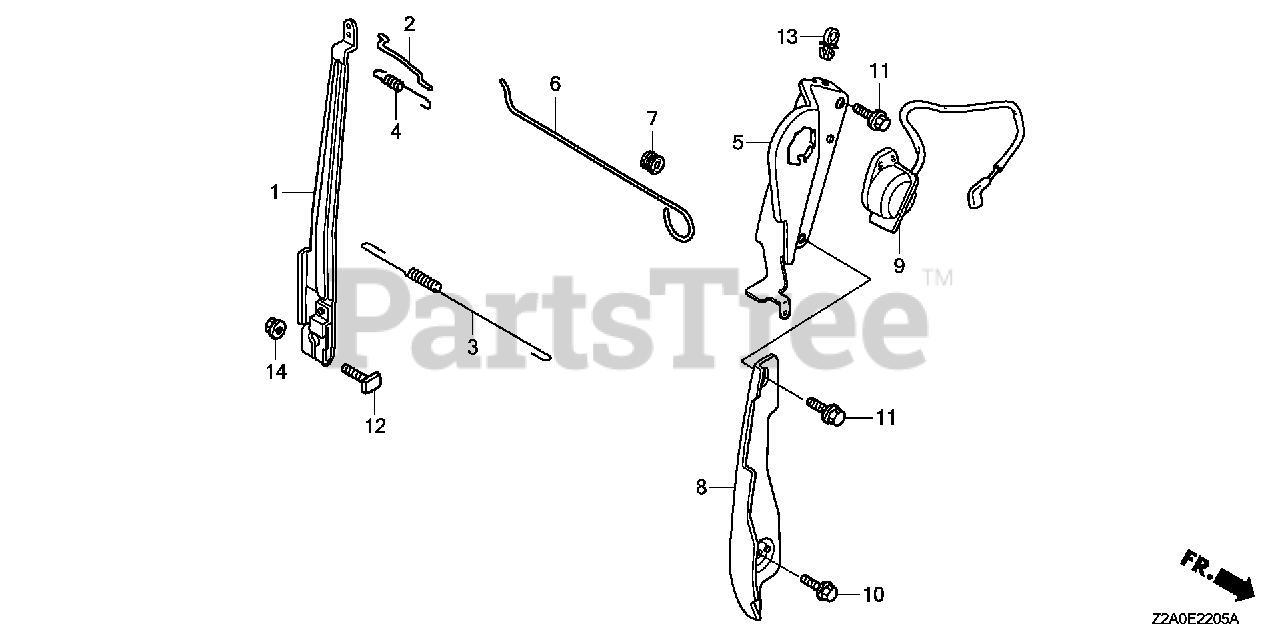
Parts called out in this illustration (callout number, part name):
1	ARM, GOVERNOR
2	ROD, GOVERNOR
3	SPRING, GOVERNOR
4	SPRING, THROTTLE RETURN
5	BASE, CONTROL
6	ROD, CHOKE CONTROL
7	GROMMET, CHOKE ROD
8	PLATE, SIDE
9	SWITCH ASSY., ENGINE STOP
10	BOLT, FLANGE (6X12) (CT200)
11	BOLT, FLANGE (6X14) (CT200)
12	BOLT, GOVERNOR ARM
13	HOLDER, WIRE (FASTEX)
13	CLIP A, CABLE (3.8MM BLACK) (NIFCO)
14	NUT, FLANGE (6MM)
